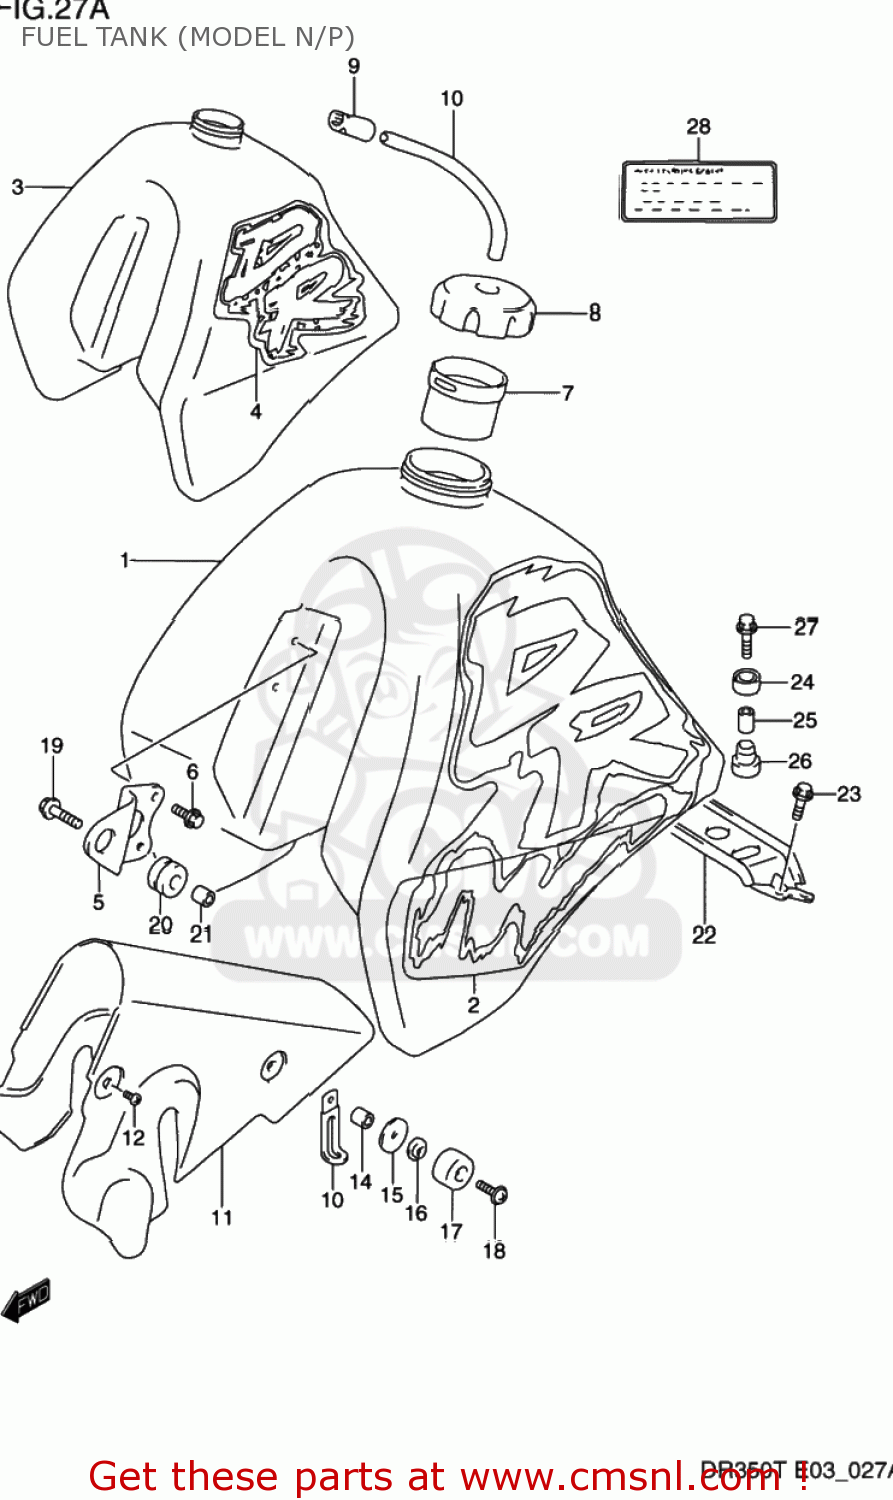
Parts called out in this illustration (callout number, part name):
1	TANK ASSEMBLY,FUEL
2	TAPE SET,FUEL TANK
3	TANK ASSEMBLY,FUEL
4	TAPE SET,FUEL TANK
5	BRACKET,FUEL TANK,FRONT
6	BOLT
7	TUBE,FILLER INLET
8	CAP ASSY,FUEL TANK
9	CLAMP,FUEL TANK BREATHER HOSE
10	HOSE(5X8.2X600)
11	HEAT SHIELD,FUEL TANK
12	SCREW
13	CLAMP
14	SPACER(6.1X14X7.2)
15	WASHER (6.5X26X2.3)
16	WASHER
17	CUSHION
18	SCREW
19	BOLT(8X25)
20	CUSHION
21	SPACER (8.8X12X12.5)
22	BRACKET,FUEL TANK RR
23	BOLT
24	CUSHION
25	SPACER
26	CUSHION
27	BOLT
28	LABEL,STARTING CAUTION
